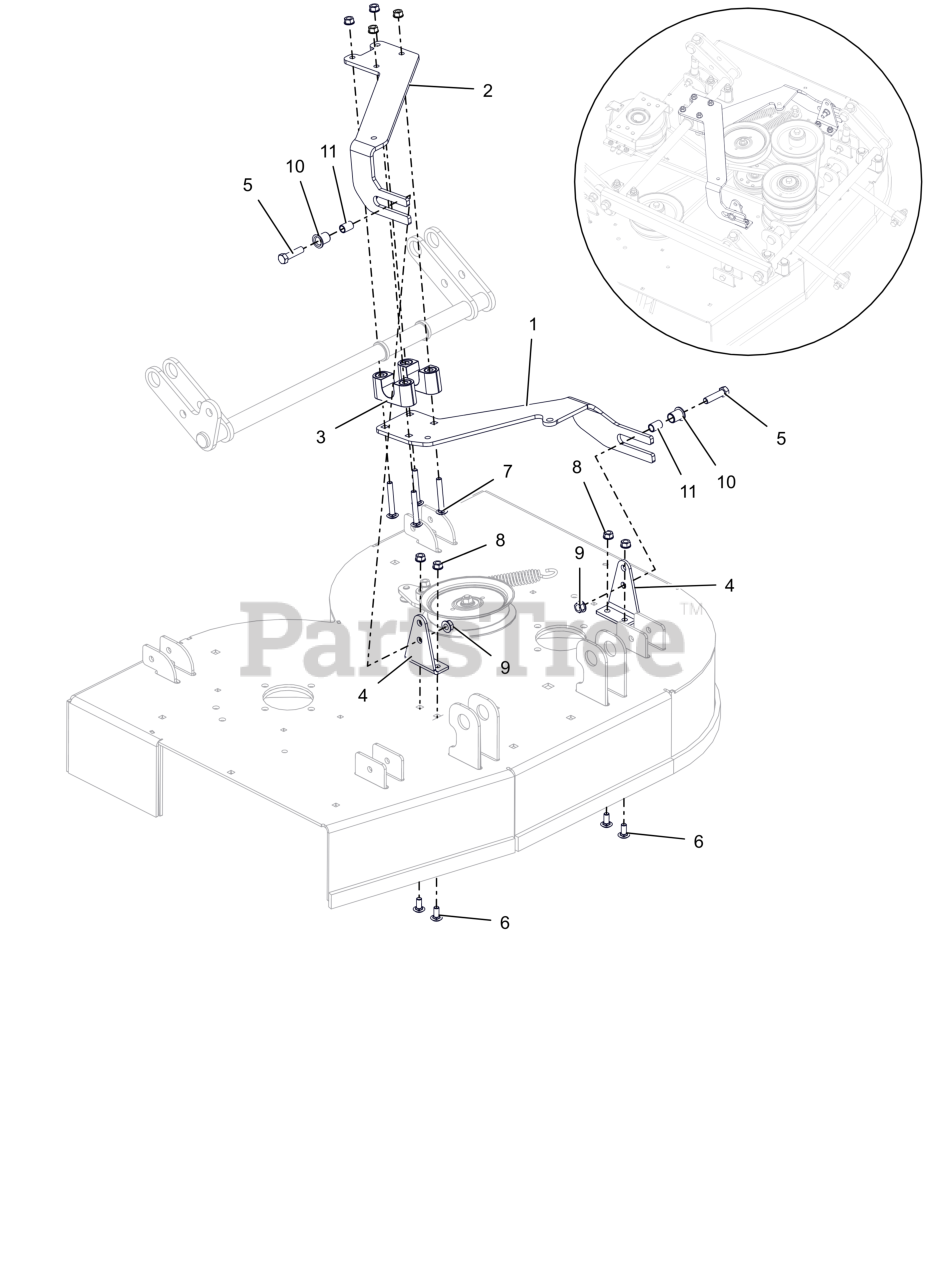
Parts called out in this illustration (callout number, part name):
1	BRKT, PIVOTING IDLER (BLACK)
2	BRKT, UPPER PIVOTING IDLER (BLACK)
3	ASM-BUSHING, DECK LIFT
4	BRKT, IDLER PIVOT (BLACK)
5	BLT, HEX .38-16X1.50 G5 ZCC
6	BLT, RHSSN.31-18X.750 G5 ZCC
7	BLT, RHSSN.31-18X2.25 G5 ZCC
8	NUT,LK-CTR-FLG .31-18 GF ZCC
9	NUT-LK-CTR-FLG .375-16 GF ZCC
10	BSHG- FLANGE .5X.625X.75X.062
11	SPCR- SLV .385 X .500 X .750
